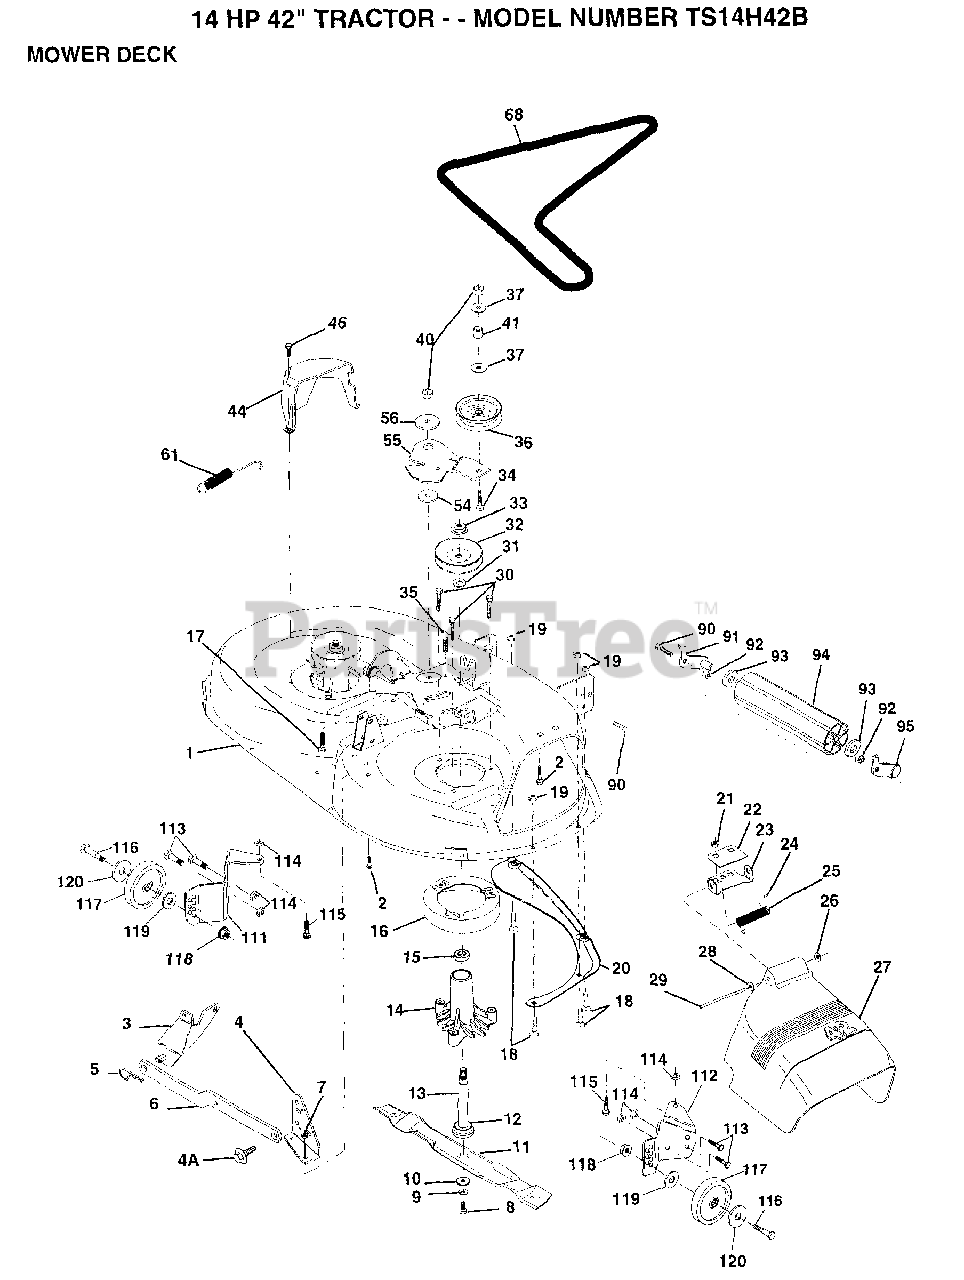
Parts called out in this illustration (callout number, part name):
2	BOLT
3	BRKT ASM SWAY BAR
4	BRKT DECK SW BAR
4A	BOLT SHD 5/16-18
7	NUT
8	BLADE BOLT
10	WASHER.HARD.BLADE
11	"BLADE.42"" MULCHER"
12	BEARING.BALL
14	HSG ASM MANDREL
15	BEARING
17	BOLT RDHD 3/8-16
18	BOLT
19	NUT
21	NUT
22	STIFFENER BRKT
23	DEFLECTOR BRKT
24	CAP-SLEEVE LT
25	SPRING TORSION
26	NUT PUSH M
27	DEFLECTOR.SHIELD
28	WASHER
29	HINGE ROD
31	WASHER
34	BOLT
35	XMAS TREE FASTNER
36	FLAT IDLER PULLEY
37	WASHER
40	NUT
44	GUARD MAND LH BLK
46	SCREW.1/4-20X5/8
54	HARDENED WASHER
56	SPACER RETAINER
61	SPRING.EXTENSION
68	BELT-V MWR 82.625
90	BOLT
93	WASHER
113	BOLT
116	BOLT M
117	WHEEL.GAGE.BLK.PL
118	LOCKNUT
119	WASHER
120	WASHER
